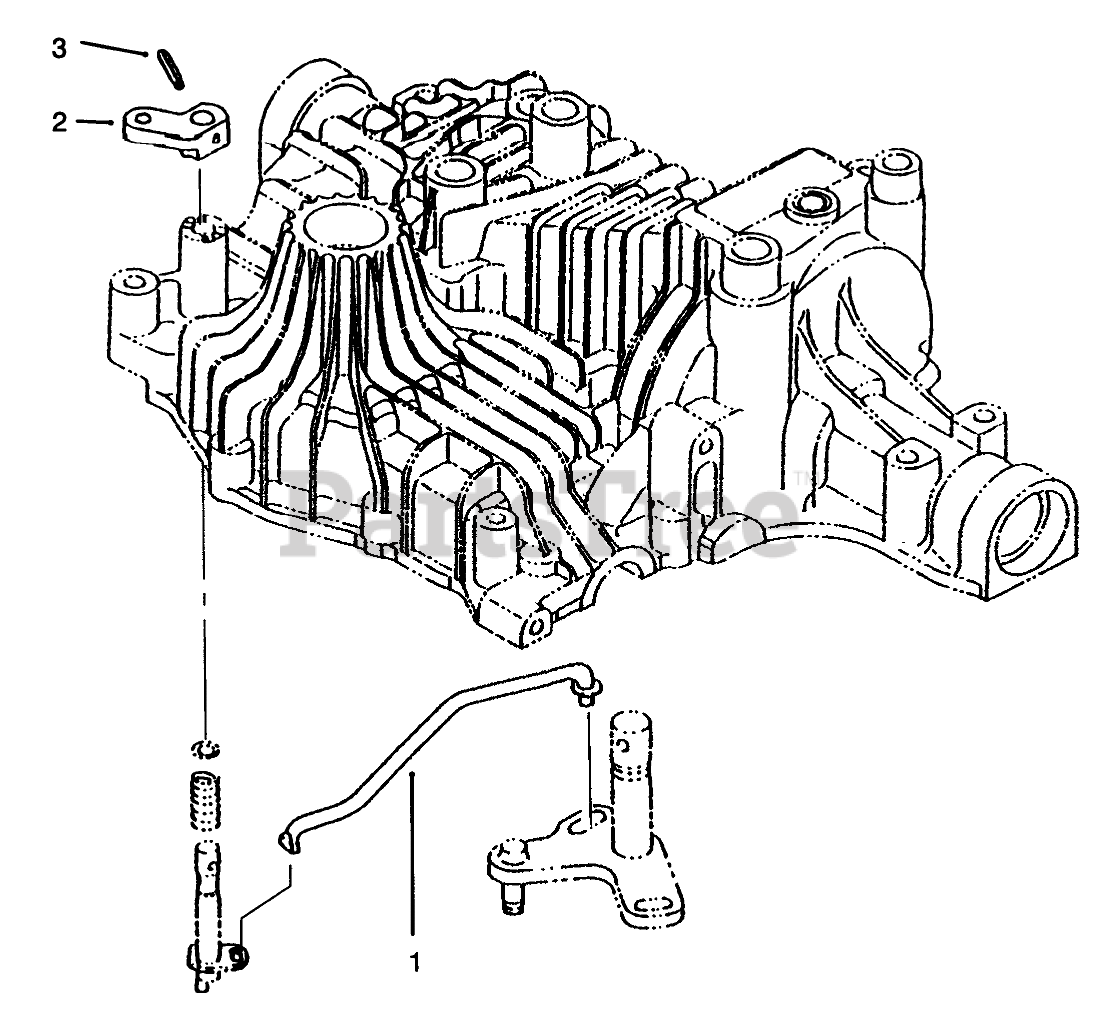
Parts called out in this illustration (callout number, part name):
1	ROD-BYPASS
2	ARM-VALVE RELEASE
3	PIN-ROLL
